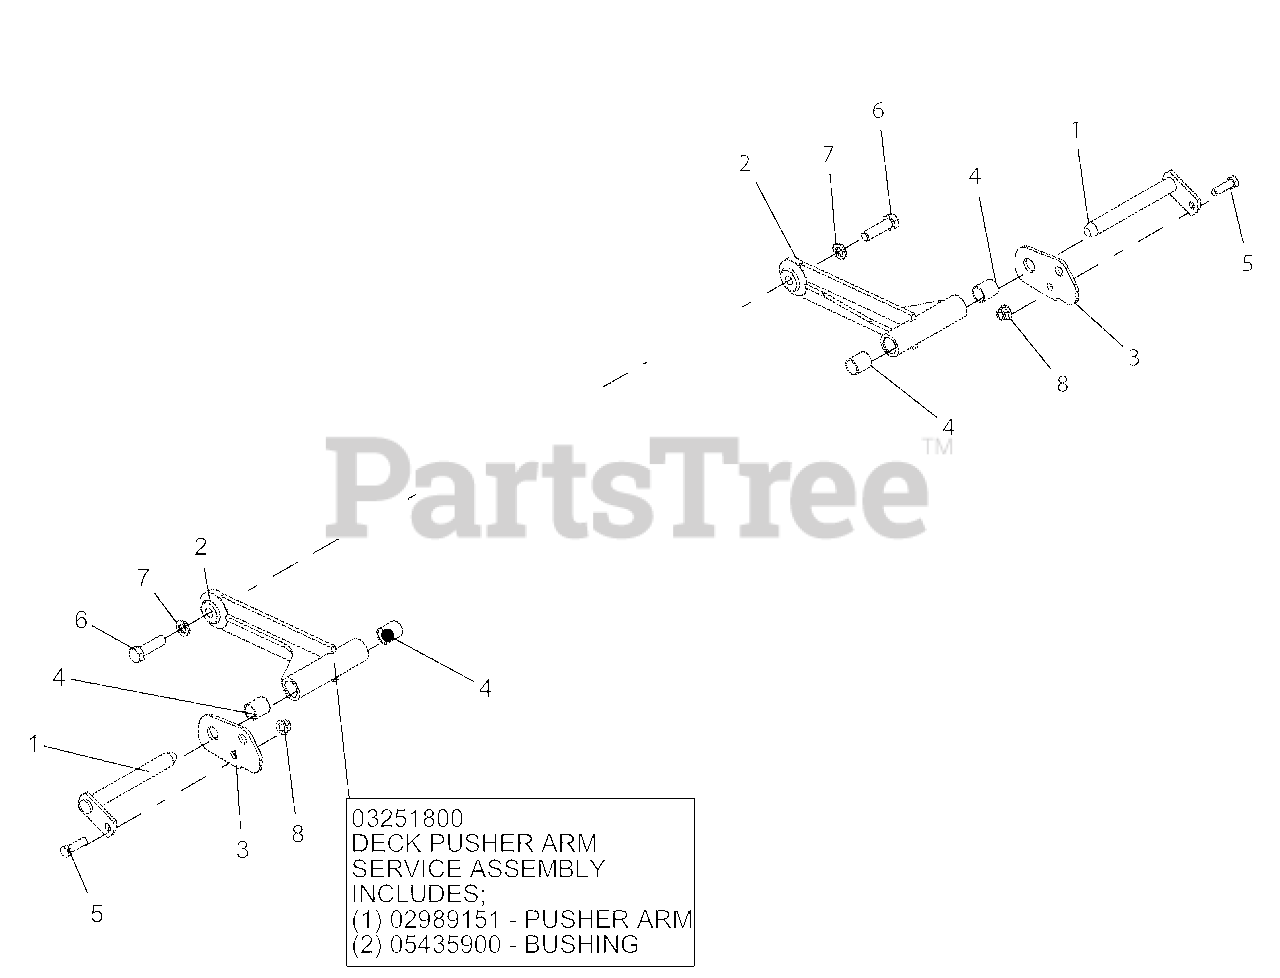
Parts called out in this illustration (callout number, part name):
1	WLDMT, MOWER MTG. PIN
2	DECK PUSHER ARM WLDMT - BLK
2	DECK PUSHER ARM SERVICE ASSEMBLY
2	PUSHER ARM
3	PLATE, PT REAR CHAIN MTG DOUBLER-RED
4	BRG, .750 X .875 X 1.000
5	BLT-HEX .38-16X1.25 GR5 YWZC
6	BLT-HEX .50-13X1.75 GR5 YWZC EP80
7	WSHR-LK .50X.125 REG YWZC
8	NUT-LK-NYL-FLG .38-16 YWZC
